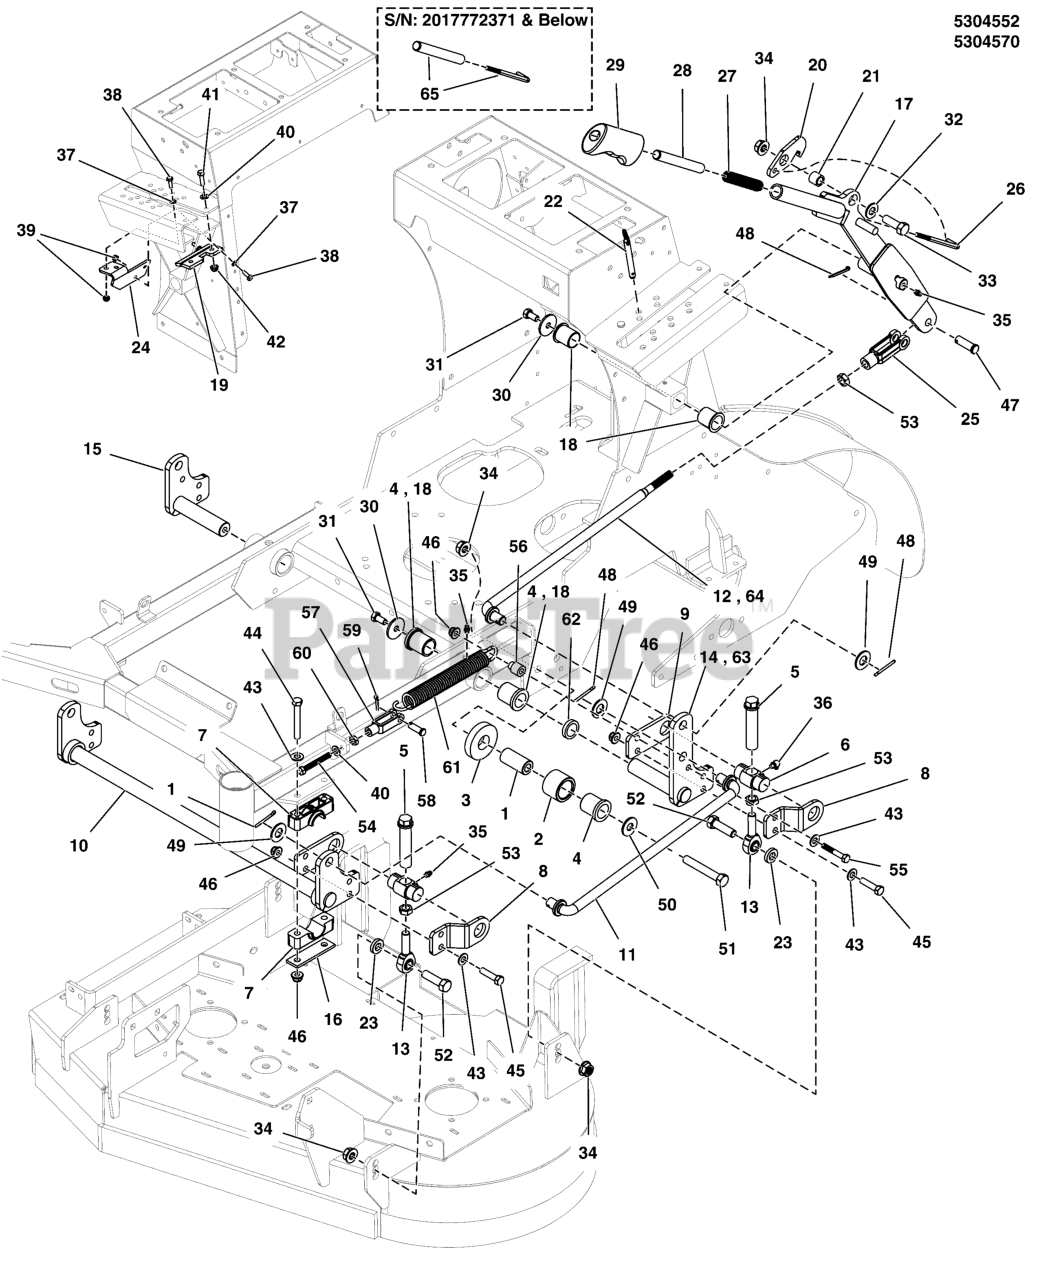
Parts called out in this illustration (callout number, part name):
1	SPACER, .52 X 1.00 X 2.09 - SS
2	ROLLER, DECK HEIGHT
3	WASHER, FRICTION
4	BUSHING, FLANGE
5	ADJUSTER, HEIGHT
6	PIVOT, DECK LIFT TRUNION, GREASABLE
7	PIVOT BLOCK, PLASTIC
8	BRACKET, OUTER TRUNION MNT - BLK
9	BRACKET, INNER TRUNION MNT - BLK
10	WELD, DECK LIFT SHAFT, SRSZ1 - BLK
11	ROD, DECK LIFT TIMING, SRSZ1
12	ROD, MAIN DECK LIFT, SRSZ1
13	BALL JOINT, 1/2-20, RH, MALE, METAL RACE
14	WELD, REAR LIFT PIVOT, LH - BLK
15	WELD, REAR LIFT PIVOT, RH - BLK
16	PLATE, PIVOT BLOCK SUPPORT - BLK
17	WELD, DECK LIFT, STAND ON - BLK
18	BUSHING, 1.00 X 1.13 X 1.38, PLASTIC
19	PLATE, LATCH GUIDE - BLK
20	PLATE, LATCH, PUSH BUTTON LIFT - BLK
21	SPACER, .50 X .75 X .66, CZ
22	PIN, HITCH, 3/8" DIA X 2.5" EL, CZ
23	WASHER, .515 X 1.00 X .25", CZ
24	PLATE, BRACKET, DECK LIFT SUPPORT - BLK
25	CLEVIS, 1/2-20, STEEL, CLEAR ZINC
26	ROD, DECK LIFT LATCH
27	SPRING-COMP 0.715ODX 03.85 LG
28	BUTTON, PUSH, DECK LIFT, THREADED
29	GRIP,LIFT LEVER
30	WASHER, .390 X 1.50 X .109, CZ
31	BOLT, 3/8-16 X 3/4, PLT W/PATCH
32	WASHER, 1/2 SAE
33	BOLT, 1/2-13 X 1-1/2 GD5 CZ
34	NUT, Hex Flange, Nylock, 1/2-13
35	GREASE FITTING, 1/4-28 STRAIGHT
36	GREASE FITTING, 1/4-28, 90 DEGREE
37	WASHER, 1/4 SAE
38	BOLT, 1/4-20 X 3/4 GD5 CZ
39	NUT, 1/4-20 HEX NYLOCK FLANGE
40	WASHER, 5/16" SAE
41	BOLT, 5/16-18 X 1 GD5 CZ
42	NUT, 5/16-18 HEX NYLOCK FLANGE
43	WASHER, 3/8 SAE
44	BOLT, 3/8-16 X 2-3/4" GD5 CZ
45	BOLT, 3/8-16 X 1-1/2" GD5 CZ
46	NUT, 3/8-16 HEX NYLOCK FLANGE
47	PIN, CLEVIS, 1/2 X 1-1/2, CL/ZC
48	PIN, COTTER, 1/8 X 1-1/4
49	WASHER, 5/8 SAE
50	WASHER, 1/2 USS
51	BOLT, 1/2-13 X 3-1/4, HEX HD, GD5, CZ (SV)
52	BOLT, 1/2-13 X 1-3/4 GD5 CZ
53	NUT, 1/2-20 HEX JAM
54	BOLT, 5/16-18 X 2-1/2 GD5 TFL, CZ
55	HHCS, 3/8-16 X 2.00, GR5, ZINC/CLEAR
56	SPACER,3/8X3/4X15/16
57	CLEVIS, 5/16-18, 3/8 PIN HOLE, CLR ZINC
58	PIN, CLEVIS, 3/8 X 1-1/8, PLATED
59	PIN, 3/32 X .750, COT, ZINC/CLEAR
60	NUT, 5/16-18 HEX JAM
61	SPRING-EXTN 1.12 ODX 09.06 LG .177 ECOAT
62	SPACER, 1.02 X 1.56 X .50
63	WELD, REAR LIFT PIVOT, LH - BLK
64	ROD, MAIN DECK LIFT, 14.00
65	KIT, RELEASE BUTTON AND ROD
